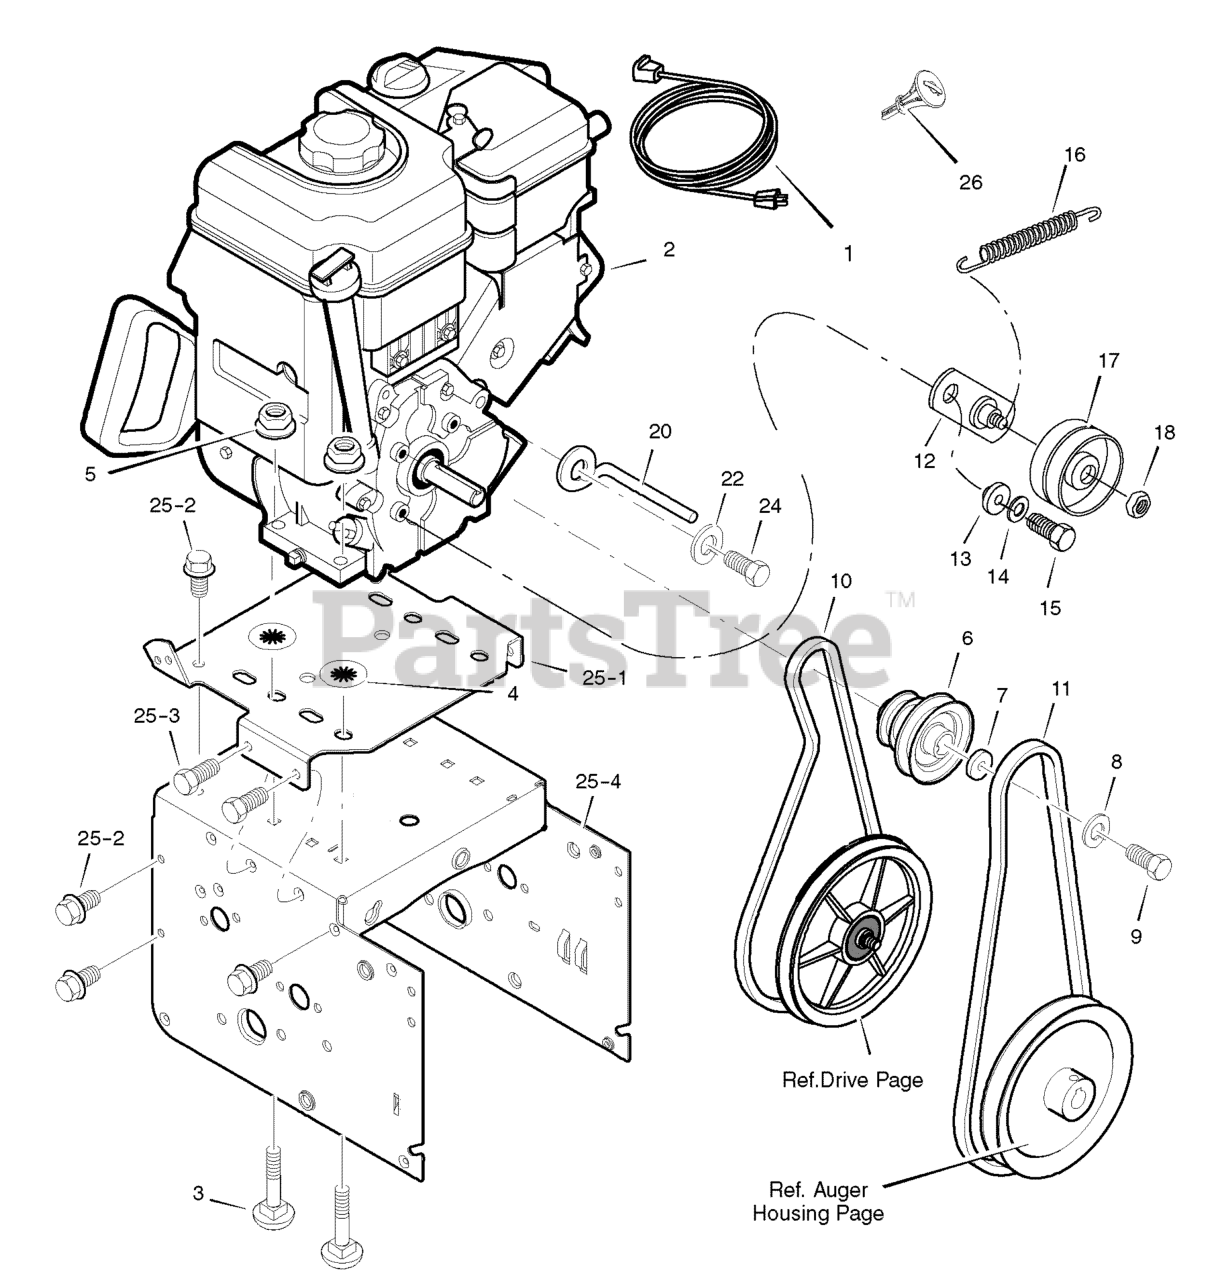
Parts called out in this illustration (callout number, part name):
1	CORD, STARTER
2	ENGINE
3	BOLT, CARRIAGE
4	RETAINER, PUSH
5	NUT
6	PULLEY, ENGINE
8	WASHER
10	V-BELT, 3L, 33.13
11	V-BELT, 4L, 38.55
12	BRACKET ASSEMBLY, IDLER
13	BUSHING, IDLER BRACKET
14	WASHER, SPLIT
15	SCREW 5/16-24 X 0.75
16	SPRING, IDLER TRACTION DRIVE
17	PULLEY, IDLER
18	NUT, JAM 3/8-16
20	GUIDE, ROD BELT
22	WASHER
25	FRAME ASSEMBLY
25-1	PLATE, ENGINE MOUNT
25-2	SCREW
25-4	FRAME, MOTOR BOX
26	KEY, BRIGGS ENGINE
